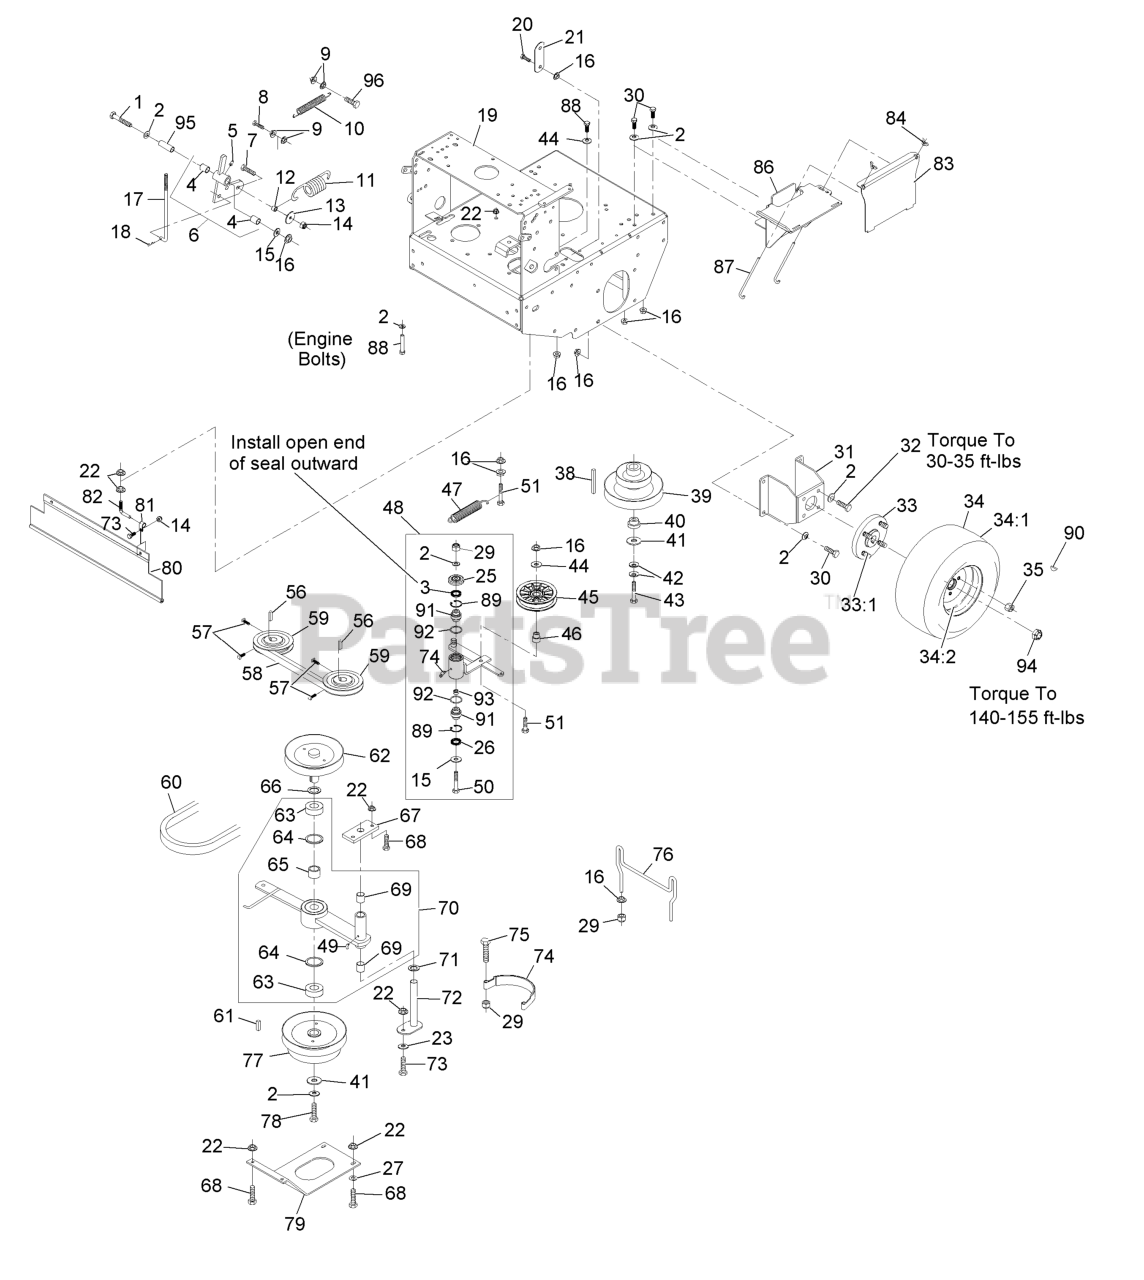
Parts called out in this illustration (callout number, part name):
1	SCREW-HH
2	WASHER-BELLEVILLE
3	SEAL-LIP, SINGLE
4	SLEEVE-BEARING
5	FITTING-GREASE
6	ASM,PIVOT W/BUSHINGS
7	SCREW-HH
8	SCREW-HH
10	SPRING,EXTENSION
11	SPRING,EXTENSION
12	SPACER,CLUTCH ANCHOR
14	NUT-LOCK, NI
15	WASHER-FLAT
16	NUT-HHF, WHIZ
17	LINKAGE,LOWER
18	PIN-COTTER
19	Asm, Deck (126-0079-01) W/Decals
20	SCREW-HH
21	ARM-LIFT, DECK
23	WASHER-SPRING
25	GUARD-TOP
26	SEAL-LIP, DOUBLE
27	WASHER-FLAT
29	NUT-LOCK, NI
30	SCREW-HH
31	WLD,MOTOR MOUNT 48&52
32	SCREW-HH
33	WHEEL HUB ASM
33:1	STUD-WHEEL
34	WHEEL AND TIRE ASM
34:1	TIRE-TURFMASTER
34:2	RIM-WHEEL
35	NUT-LUG
38	KEY,MACH 1/4X1/4X2-5/8
39	SHEAVE, DRIVE
40	BUSHING,CLUTCH KEEPER
42	WASHER-SPRING
43	SCREW-HH
44	WASHER-FLAT
45	PULLEY-IDLER, FLAT
46	BUSHING-IDLER
47	Spring, Extension
48	Kit, Idler Arm (109-1208-03) W/Brgs
49	Zerk-45deg 1/4-28
50	Screw-Hh 3/8-16 X 4 Gr8
51	Screw-Hh 3/8-16 X 1 3/4
56	Key-5mm X 5mm X 25mm
57	Screw-Set, Sqh 5/16-18 X 3/4
58	Belt, Pump Drive
59	Sheave Asm
60	Belt, Blade Clutch
61	Key-Machine 1/4 X 1/4 X 1
62	Sheave W/Shaft
63	Bearing, Clutch Shaft
64	Ring-Retaining
65	Spacer, Bearing Clutch
67	Plate, Clutch Pivot
68	Screw-Hh 5/16-18 X 1
69	Pivot, Bearing
70	Clutch Arm W/Bearings
71	Washer, Spacer
72	Pivot Pin Weldment
73	Screw-Hh 5/16-18 X 3/4
74	Band, Brake Clutch
75	Screw-Hh 3/8-16 X 1 1/2
76	Wld, Belt Guide
77	Sheave W/Drum (48")
78	Screw-Hh 3/8-24 X 1
79	Plate, Guard
80	Shield-Drag
81	Clip-Loom
82	Hanger, Drag Shield
83	Battery Cover
83	Battery, Cover
84	Wingnut-Nyloc 1/4-20
87	Bolt-Holddown
88	Screw-Hh 3/8-16 X 1 1/4
89	Ring-Retaining
90	Key-Woodruff 1 X 1/4
91	Bearing-Spherical
96	Screw-Hh 1/4-20 X 1 1/4
